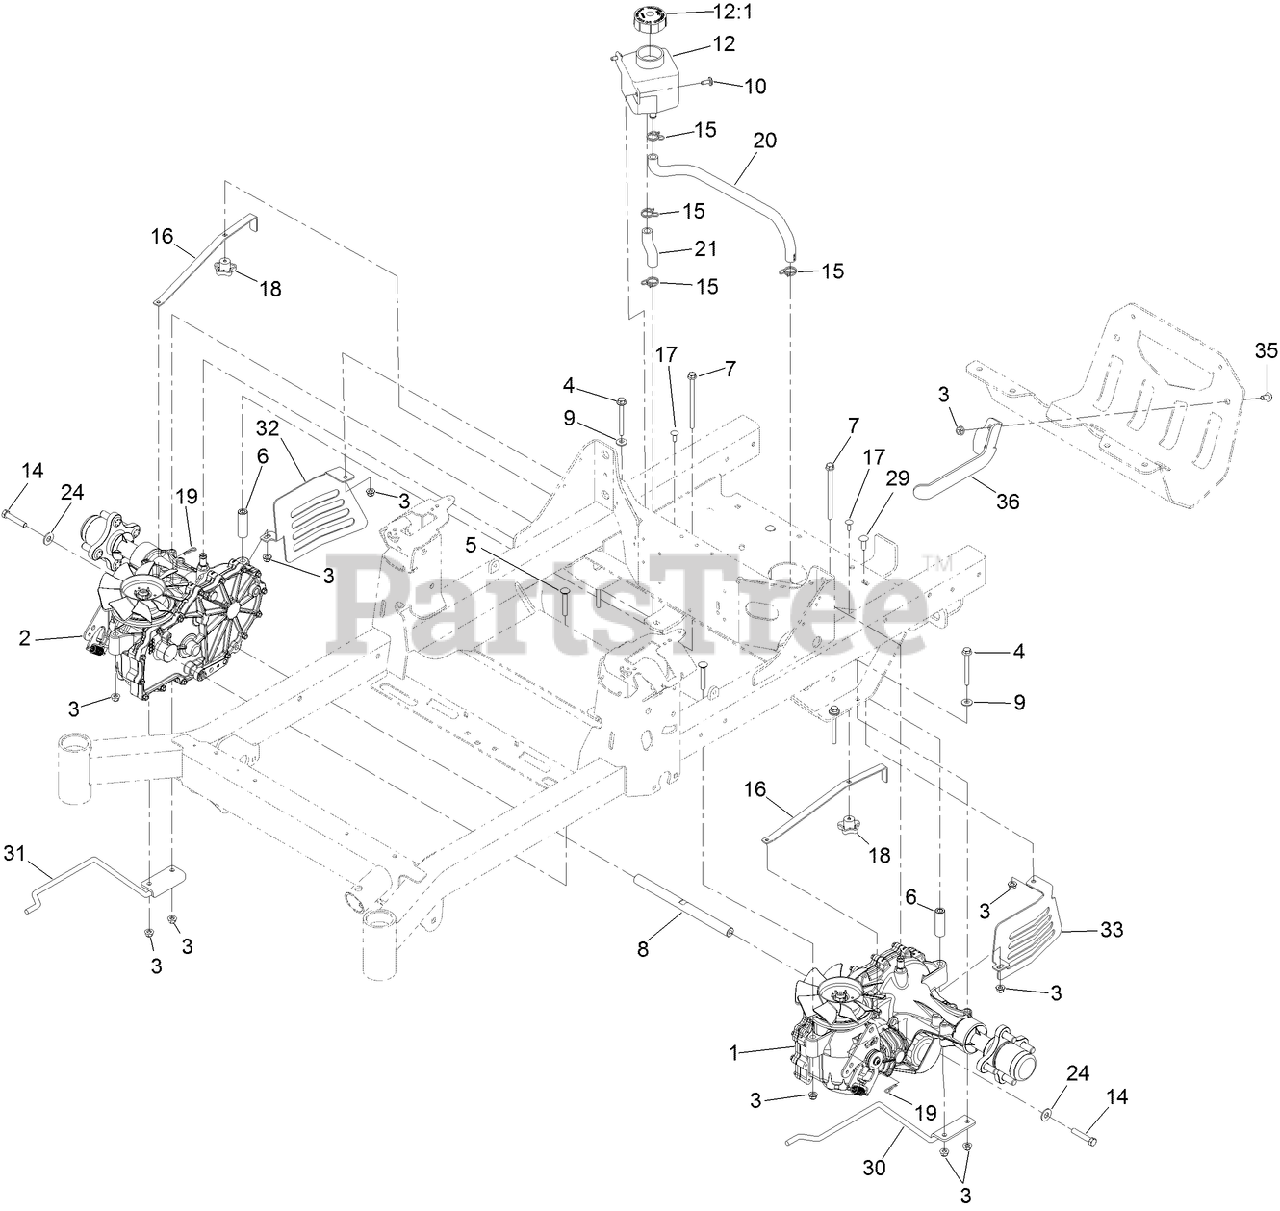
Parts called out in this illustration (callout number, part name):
1	LH TRANSAXLE ASM
2	RH TRANSAXLE ASM
3	NUT-HF, NI
4	SCREW-HHF
5	BOLT-CARR
6	SPACER-HYDRO
7	SCREW HHF
8	SHAFT-SPACER
9	WASHER-SPRING
10	SCREW-TORX
12	TANK-HYD
12:1	CAP-RESERVOIR, HYD
14	SCREW-HH W/LOCTITE
15	Clamp-Hose
16	ARM-BYPASS, HYDRO
17	BOLT-CARR
18	KNOB-HANDLE
19	PIN-COTTER
20	HOSE-HYDRAULIC
21	HOSE-HYDRAULIC
24	WASHER-FLAT
29	SCREW-CARR
30	SUPPORT-UPPER, LH
31	SUPPORT-UPPER, RH
32	GUARD-CLUTCH, RH
33	GUARD-CLUTCH, LH
35	SCREW-TORX
36	BRACKET-GUARD, MUFFLER
